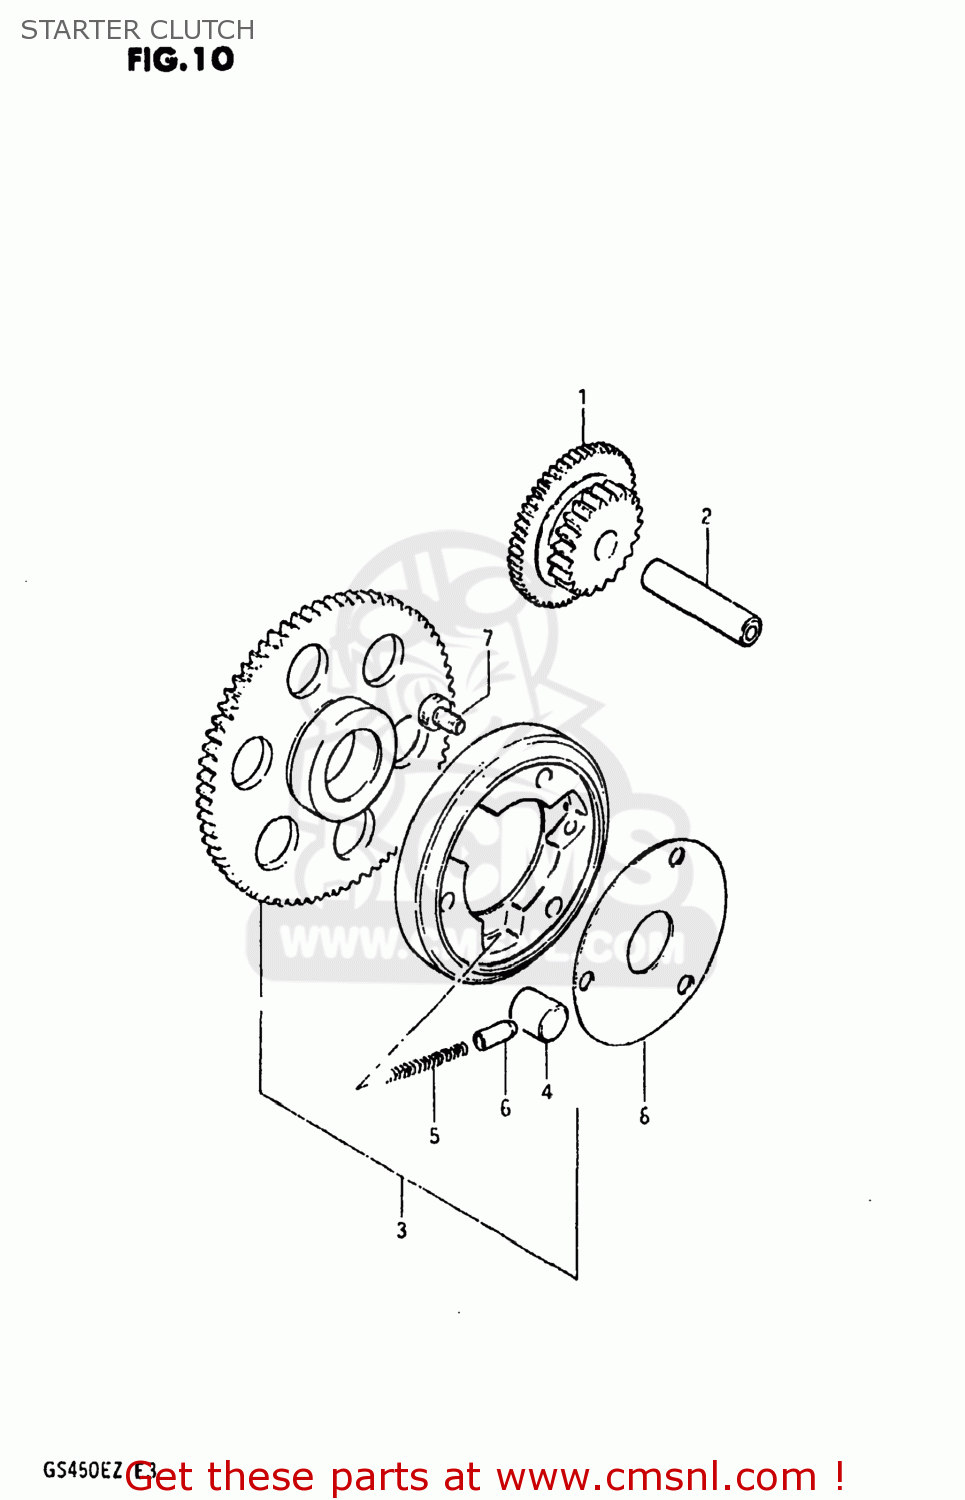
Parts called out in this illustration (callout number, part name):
1	GEAR,STARTER IDLE
2	PIN(7.4X13X56)
3	CLUTCH SET,STARTER
4	ROLLER(15X13)
5	SPRING
6	PIECE,PUSH
7	BOLT
8	SHIM,STARTER CLUTCH HUB
